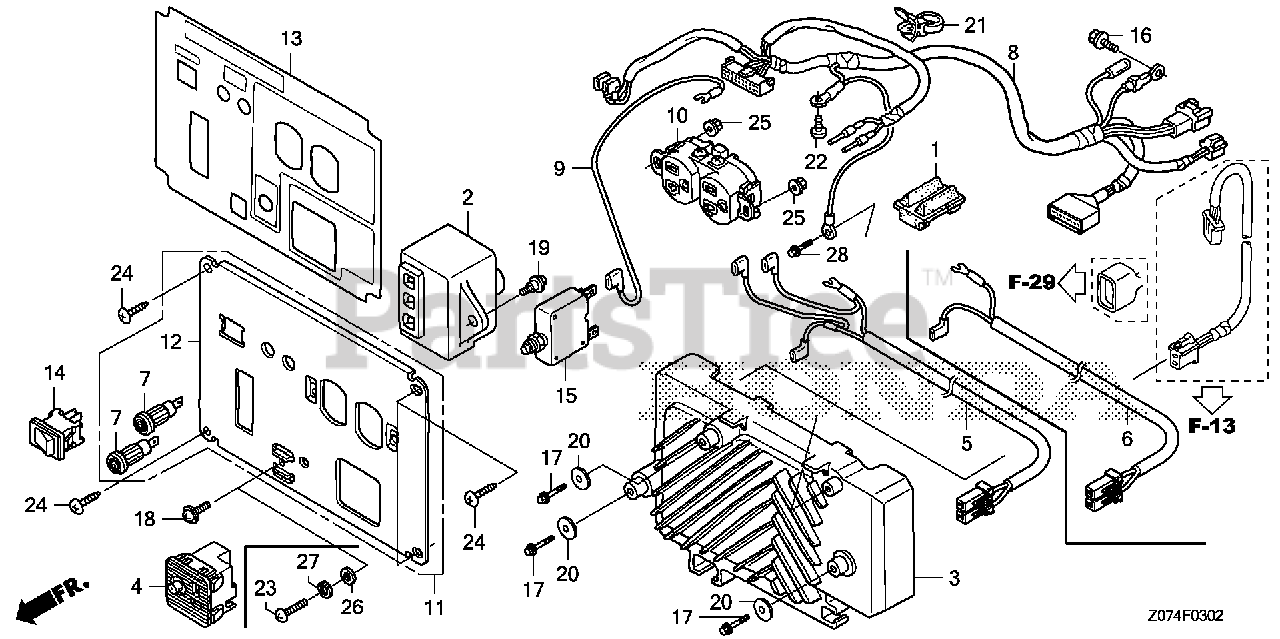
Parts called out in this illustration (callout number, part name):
1	RUBBER B, TANK MOUNTING
2	SPARK UNIT
3	INVERTER UNIT
4	RECEPTACLE, D.C.
5	SUB-WIRE HARNESS ASSY.
7	SOCKET, COMPOSITE
8	WIRE HARNESS ASSY., CONTROL
9	WIRE, TERMINAL
10	RECEPTACLE ASSY. (20A/125V) (MATSUSHITA)
11	PANEL, CONTROL
12	PANEL, CONTROL
13	MARK, CONTROL PANEL
14	SWITCH, AUTO-THROTTLE
15	PROTECTOR, CIRCUIT (20A) (WHITE)(TYCO)
16	BOLT, FLANGE (5X10)
17	BOLT, FLANGE (5X12)
18	SCREW, PAN (5X12)
19	SCREW, PAN (5X13)
20	WASHER, PLAIN (20MM)
21	BAND (100MM) (BLACK)
22	SCREW, PAN (5X8)
24	SCREW, TAPPING (5X16) (PO)
25	NUT, FLANGE (4MM)
28	BOLT, FLANGE (5X10)
